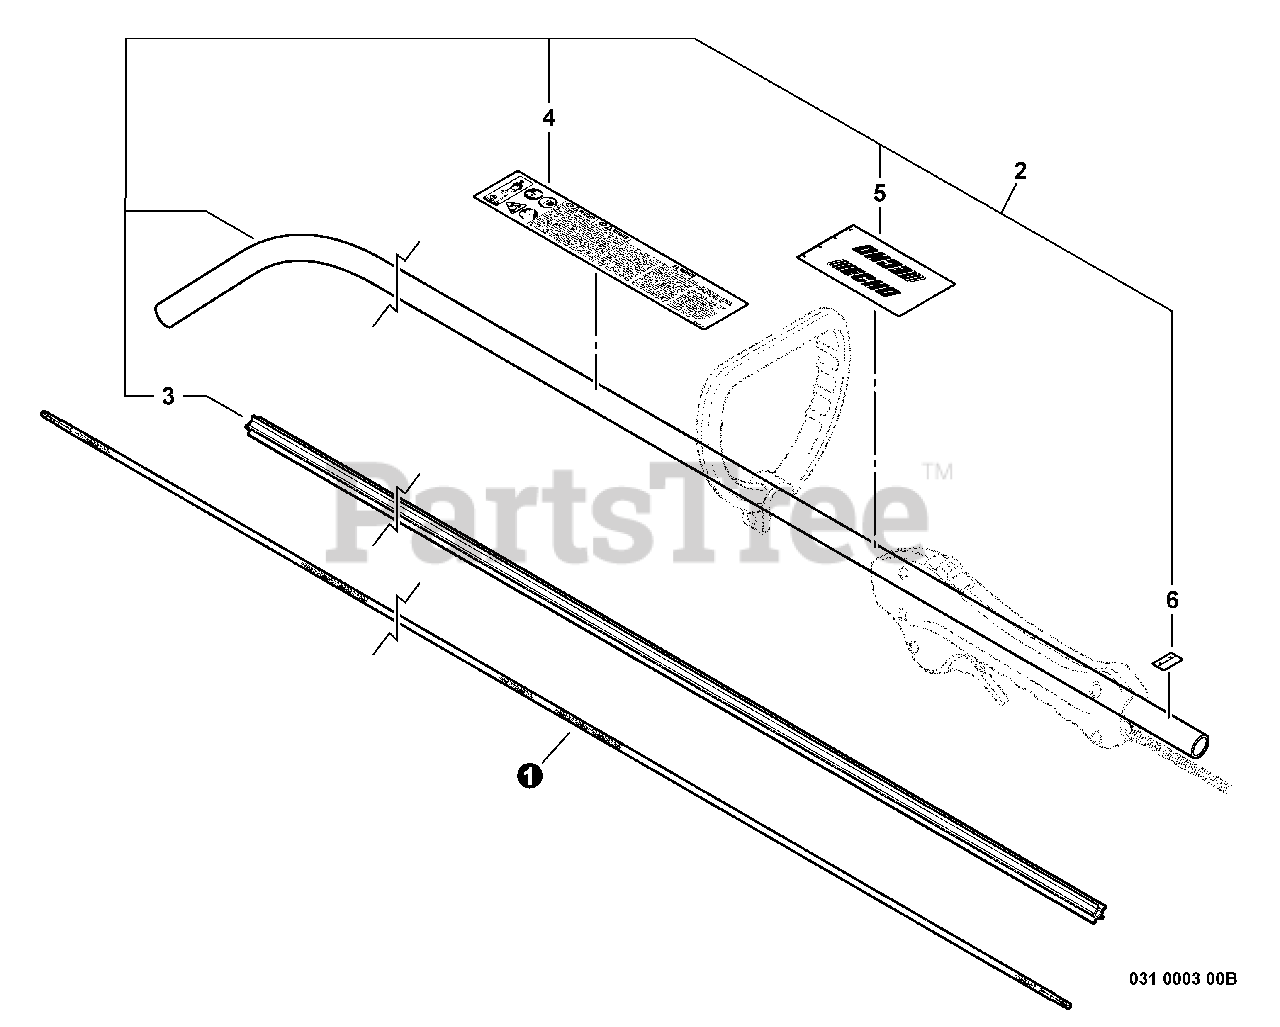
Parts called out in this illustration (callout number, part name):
1	DRIVESHAFT - FLEXIBLE
2	MAIN PIPE ASSY
3	LINER - FLEXIBLE
4	LABEL, CAUTION
5	LABEL, HANDLE LOCATION
6	LABEL - ALIGNMENT
